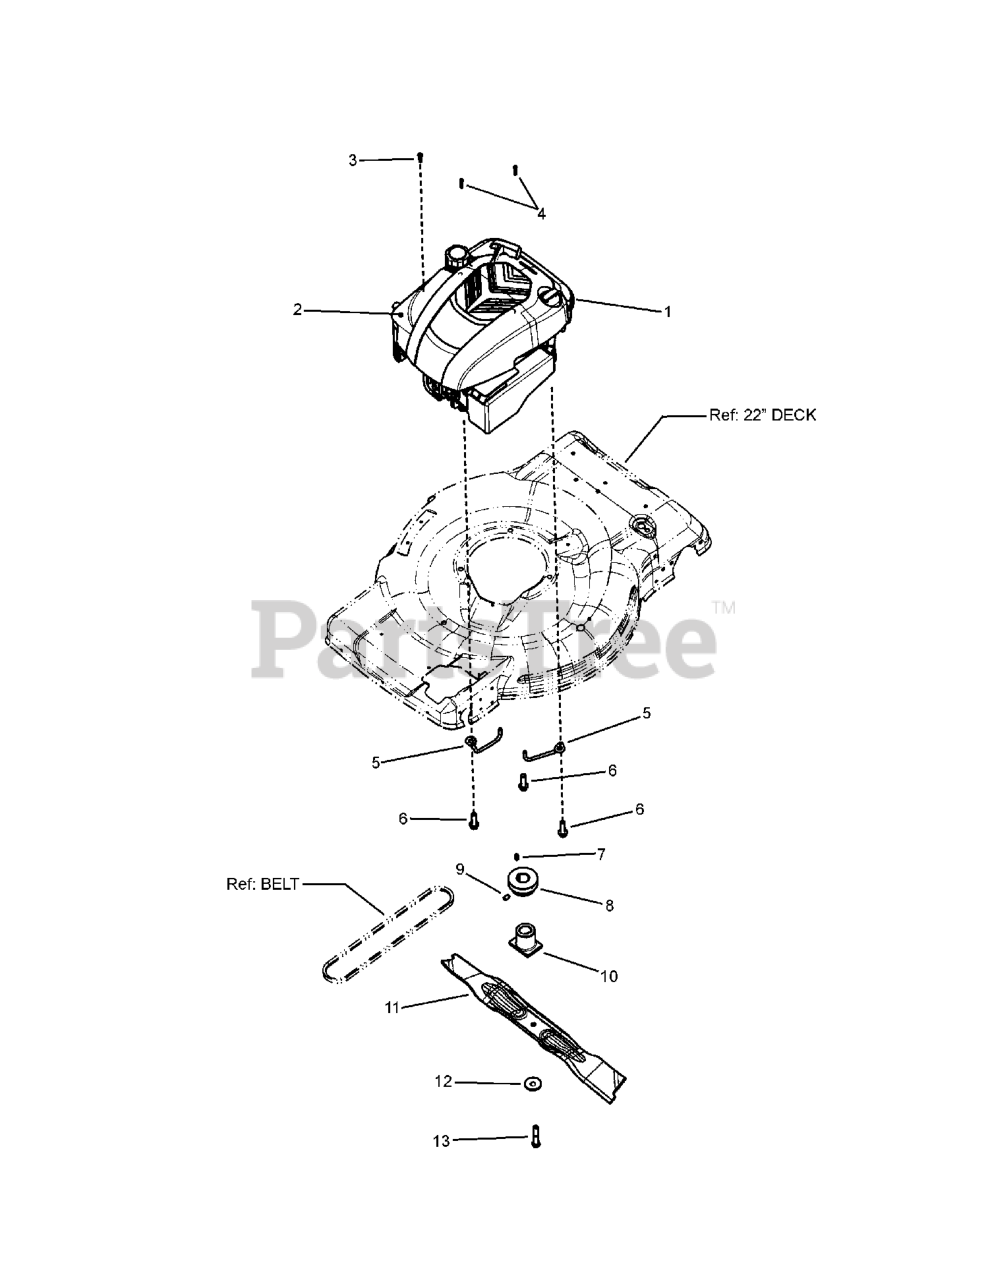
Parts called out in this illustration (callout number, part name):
1	ENGINE, 700 SERIES, QUANTUM, DEERE, FC
2	COVER, CONTROL (P-290 BLACK)
3	SCREW, PAN HEAD THREAD ROLLING
4	SCREW, PAN HD CROSS RECESS, TAPPING
5	BELT GUIDE, ENGINE, FWD
6	HWST, 3/8-16 X 1.25
7	KEY, #HP-506 HI-PRO
8	PULLEY, ENGINE
9	HRSS, 5/16-18X1/2
10	HUB, BLADE, 21" WBM, RD, 2 POSITION
11	BLADE, 22", WAVE, DEERE, STEEL DECK
12	WASHER, CONE
13	HHCS, 3/8-24X2 GR5
